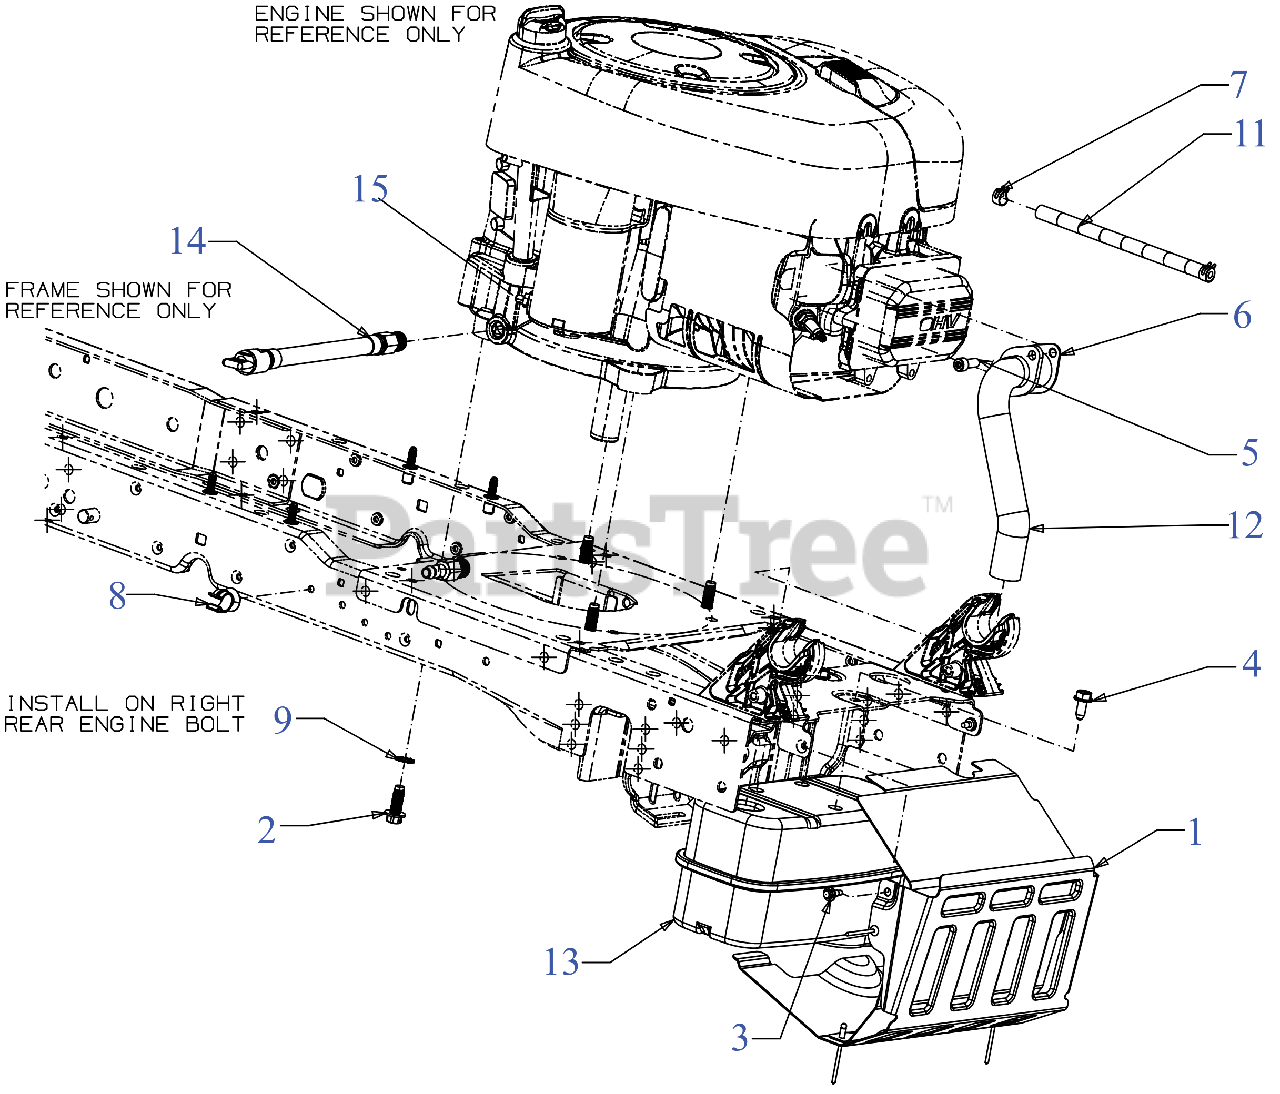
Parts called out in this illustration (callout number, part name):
1	MUFFLER SHIELD ASSEMBLY
2	SCREW 3/8-16 x 1
3	SCREW M6-1 x .625
4	SCREW M8-1.25 x .750
5	SCREW 5/16-18 x .625
6	EXHAUST GASKET
7	HOSE CLAMP 1/20
8	DRAIN HOSE CLIP
9	LOCK WASHER 3/8
11	FUEL HOSE LOW PERMEATION
12	EXHAUST PIPE (B&S) (SINGLE)
13	EXHAUST MUFFLER (SINGLE)
14	OIL DRAIN KIT (TWIN)
14	OIL DRAIN KIT
15	HEX NUT 1/4-20
